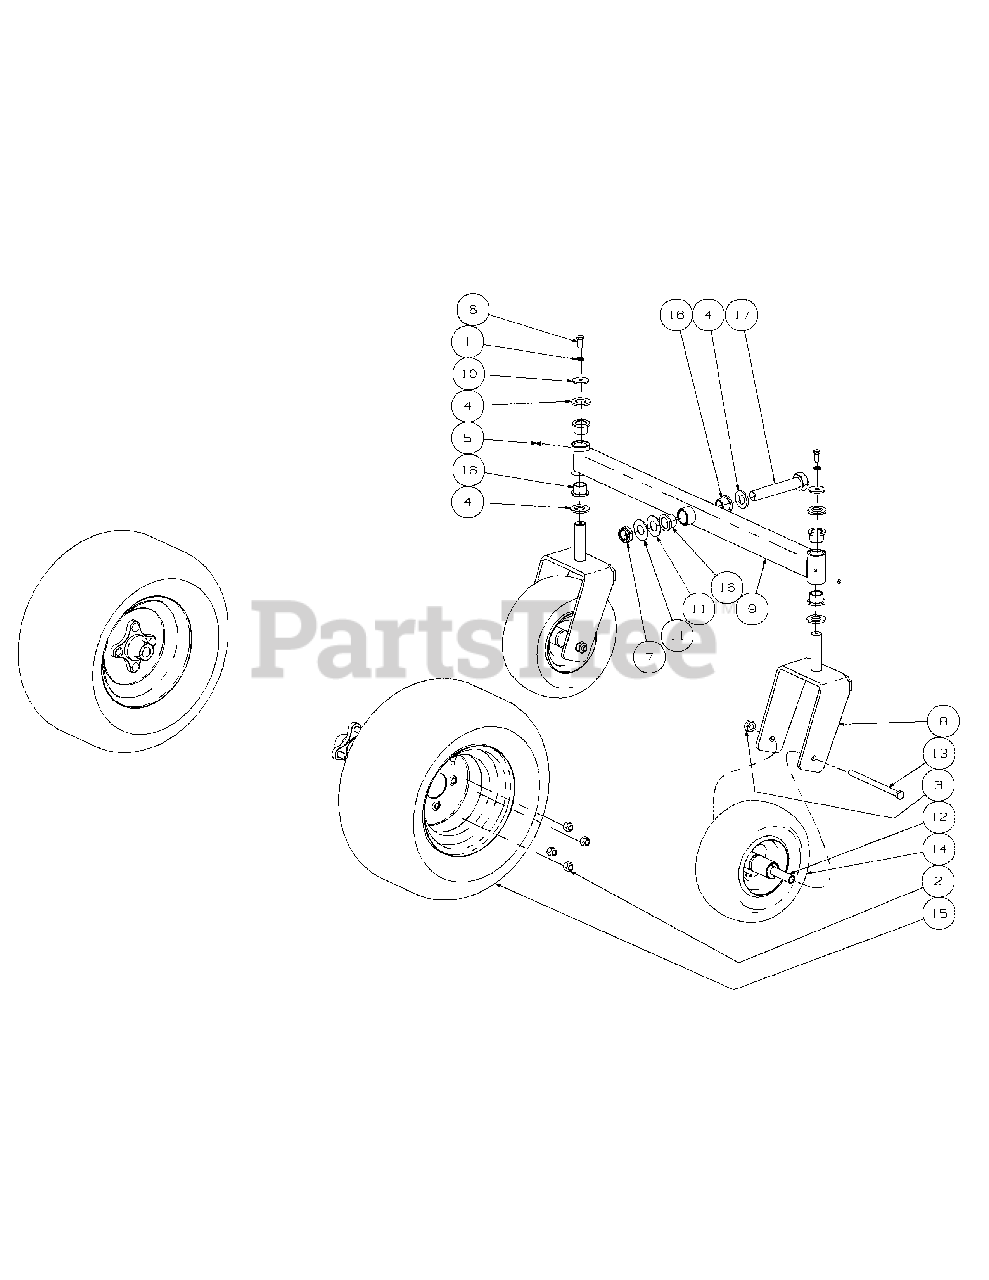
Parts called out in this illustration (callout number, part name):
1	Lock Washer, 3/8 Zinc
2	Lug Nut, 1/2-20
3	Lock Nut, Nylon Insert, 1/2-20
4	Washer Special
5	Grease Fitting, 1/4-28 x 3/16
6	Hex Cap Screw, 3/8-16 x .88
7	Nut Jam, 1.0-14, Nylon Insert
8	Castor Wheel Mounting Bracket
9	Front Axle Assembly
10	Flat Washer, .390 x 1.5 x .134
11	Flat Washer, 1.00 ID x 2.25 OD x ,075
12	Wheel Spacer
13	Hex Cap Screw, 1/2-20 x 7.50
14	Wheel Assembly 11 x 6.00 - 5, Beige
15	Wheel Assembly, 20 x 10.00 x 10
16	Flange Bearing, 1.001 x 1.25
17	Hex Cap Screw, 1-14 x 5.5
